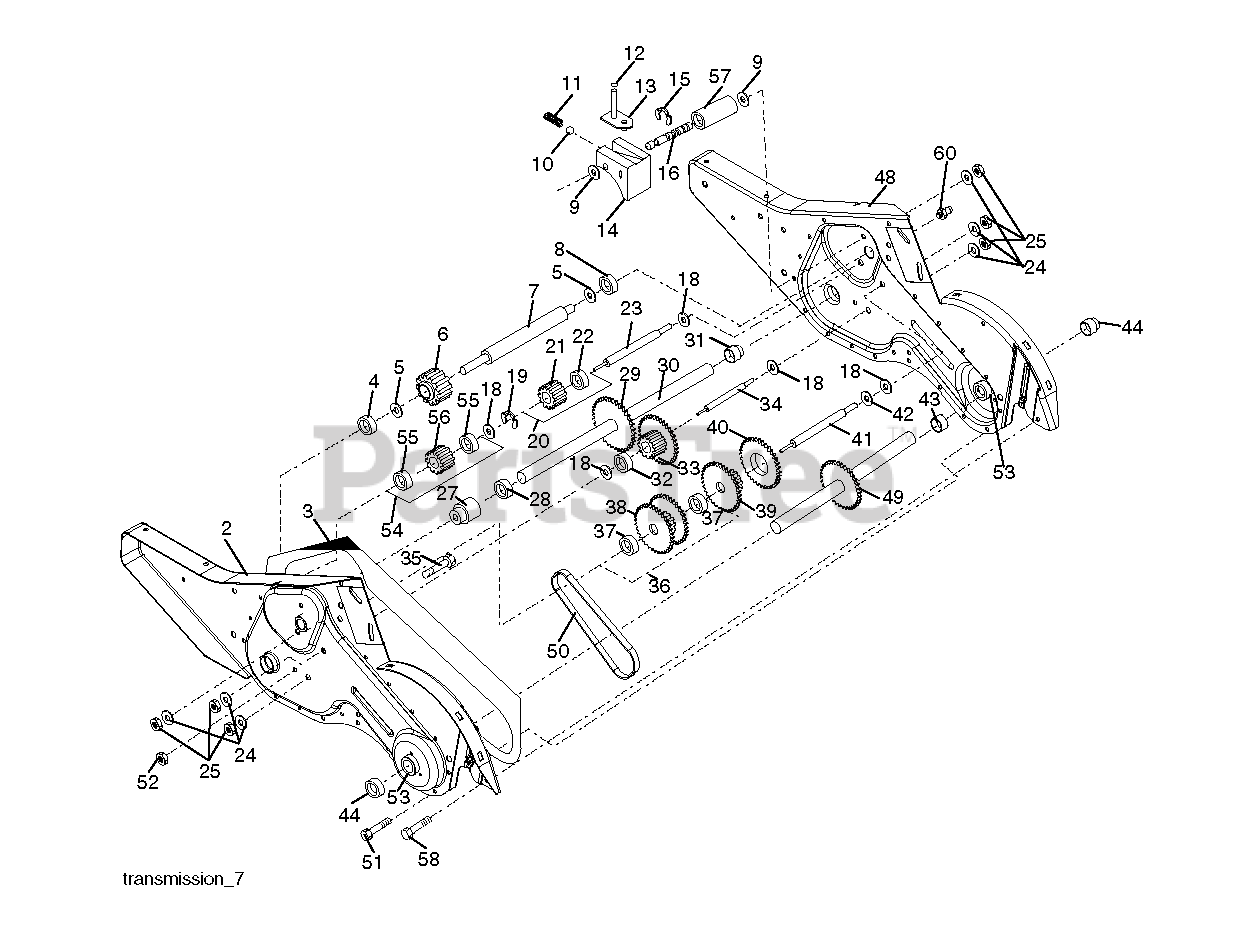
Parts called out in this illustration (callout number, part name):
2	GEARCASE.ASM.DRT.LH.
3	GASKET.GEARCASE.CRT/DRT.TILLER
4	NEEDLE BRNG LT
5	THRUST WASHER
6	GEAR.PINION.INPUT.DRT
7	SHAFT.INPUT.D.9TEETH
9	WASHER, SEAL
10	BALL, STEEL
11	SPRING-SHIFT CRT
12	O-RING TI
13	SHIFTING ARM
14	SHIFT FORK TI
15	KLIP RING
16	SHAFT.SHIFT.DRT
19	KLIP RING
20	GEAR ASSY CRT
21	GEAR-REV IDLR CRT
22	NEEDLE BEARING TI
23	SHAFT.IDLER.REVERSE.CRT
27	BEARING, SHAFT LH CRT
29	CHAIN CRT
30	GROUND SHAFT ASS'Y
31	BEARING, SHAFT RH CRT
32	SPACER TI
33	SPRCKT 8 GEAR CRT
34	SHAFT.SECONDARY.REDUCTION.CRT
35	SCRW WHIZ LOK CRT
36	GEAR & SPROCKET.ASM.WBEARIN
37	BEARING.NEEDLE.CRT
38	ASM.GEAR & SPROCKET
39	GEAR.CLUSTER.DRT.TILLER
41	SHAFT.REDUCTION.FIRST.DRT
42	BRNG RACE T
43	SPACER TI
44	SEAL ASM, OIL
48	GEARCASE.ASM.DRT.RH.
49	SHAFT.ASM.TINE
50	CHAIN.TILLER
51	SCREW
53	BEARING KIT
54	GEAR.ASM.DRT.TILLER
55	BEARING.NEEDLE
56	GEAR.DRT.IDLER
57	SPACER.SPLIT
58	BOLT SHOULDER 1/4-20 UNC X.875
60	FITTING.GREASE.TAPERED
